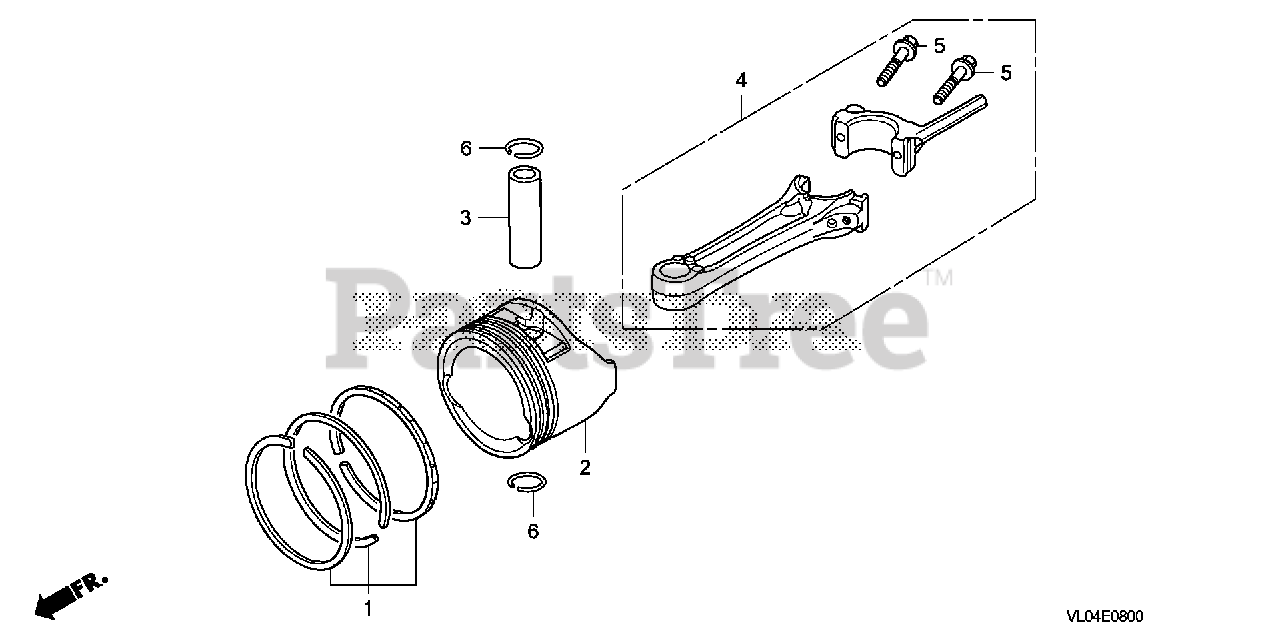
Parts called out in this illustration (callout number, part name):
1	RING SET, PISTON (STD) (TEIKOKU)
2	PISTON
3	PIN, PISTON
4	ROD ASSY., CONNECTING
5	BOLT, CONNECTING ROD
6	CLIP, PISTON PIN (13MM)
